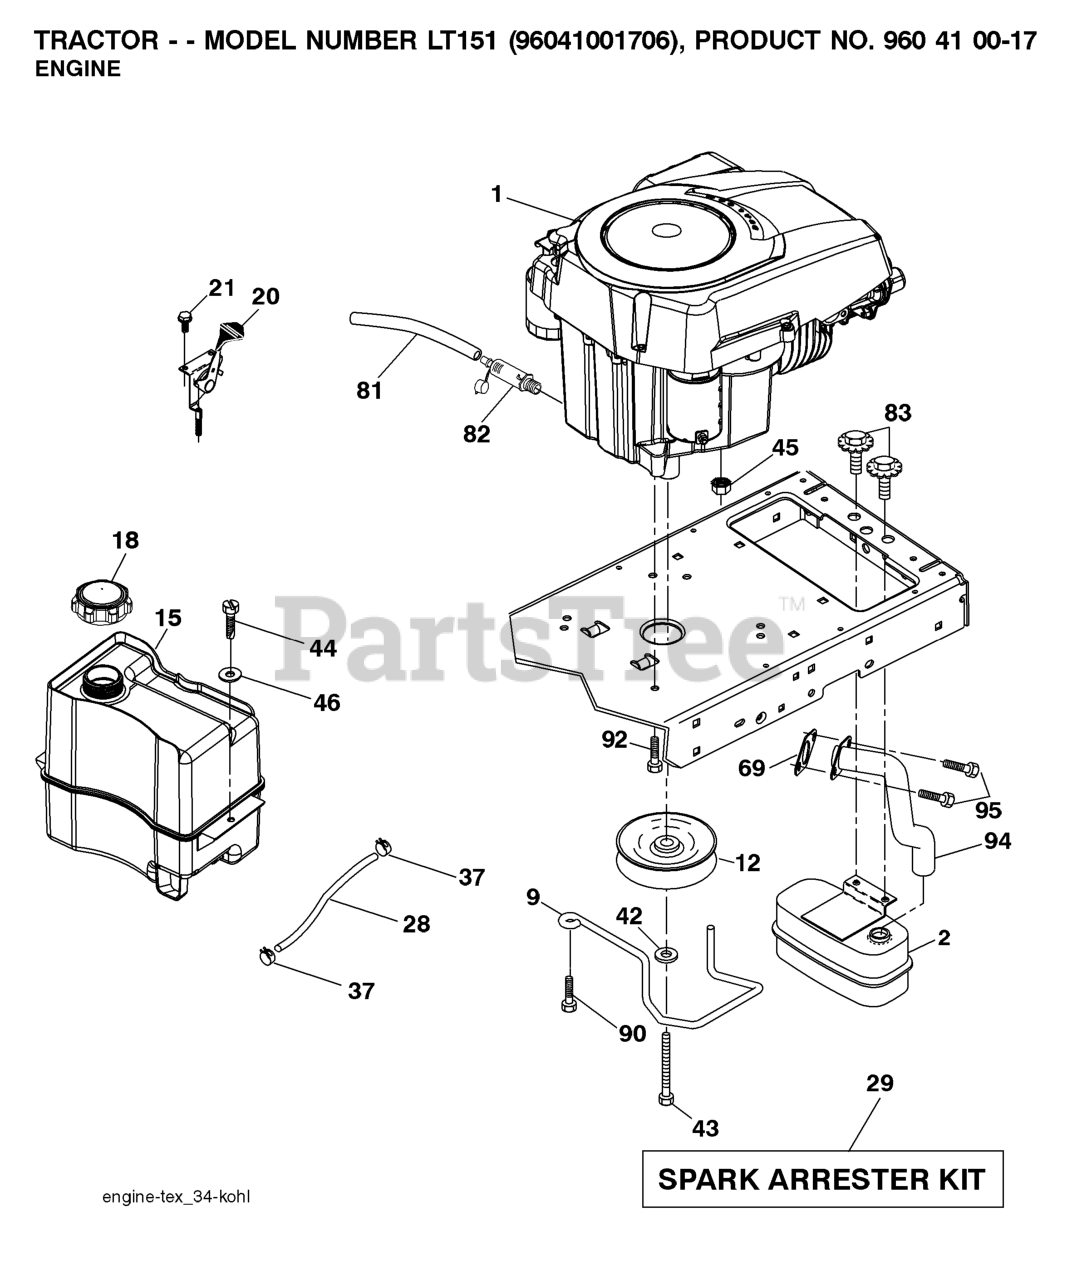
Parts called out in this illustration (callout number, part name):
2	MUFFLER.SINGLE.CYL.KOHL/B&S
9	KEEPER.BELT.ENGINE.3.25 (3 2)
12	PULLEY ENGINE
15	RP TANK FUEL FRT 1.5 GAL
18	FUEL CAP
20	CONTROL.TH/CK.C.
21	SCREW.#10 X 0.750.BOS
28	LINE.FUEL.20
29	KIT.SPARK ARRESTOR 794945 B&S
37	HOSE CLAMP
41	LOCKWASHER
43	BOLT HEX 7/16-20X4-1/4"
44	SCREW HEXWSHR 1/4-20X3/4
45	NUT
69	GASKET.EXHAUST.KOHLER
81	TUBE, DRAIN OIL ASM.
82	PLUG DRAIN OIL EASY
83	BOLT.5/16-18UNCX3/4 W/SEMS.BLK
90	SCREW 3/8-16X1
92	SCREW 3/8-16X1
94	RP.TUBE.EXHAUST.KOHL.COURAGE
95	SCREW.SOCKET HD.5/16-1
